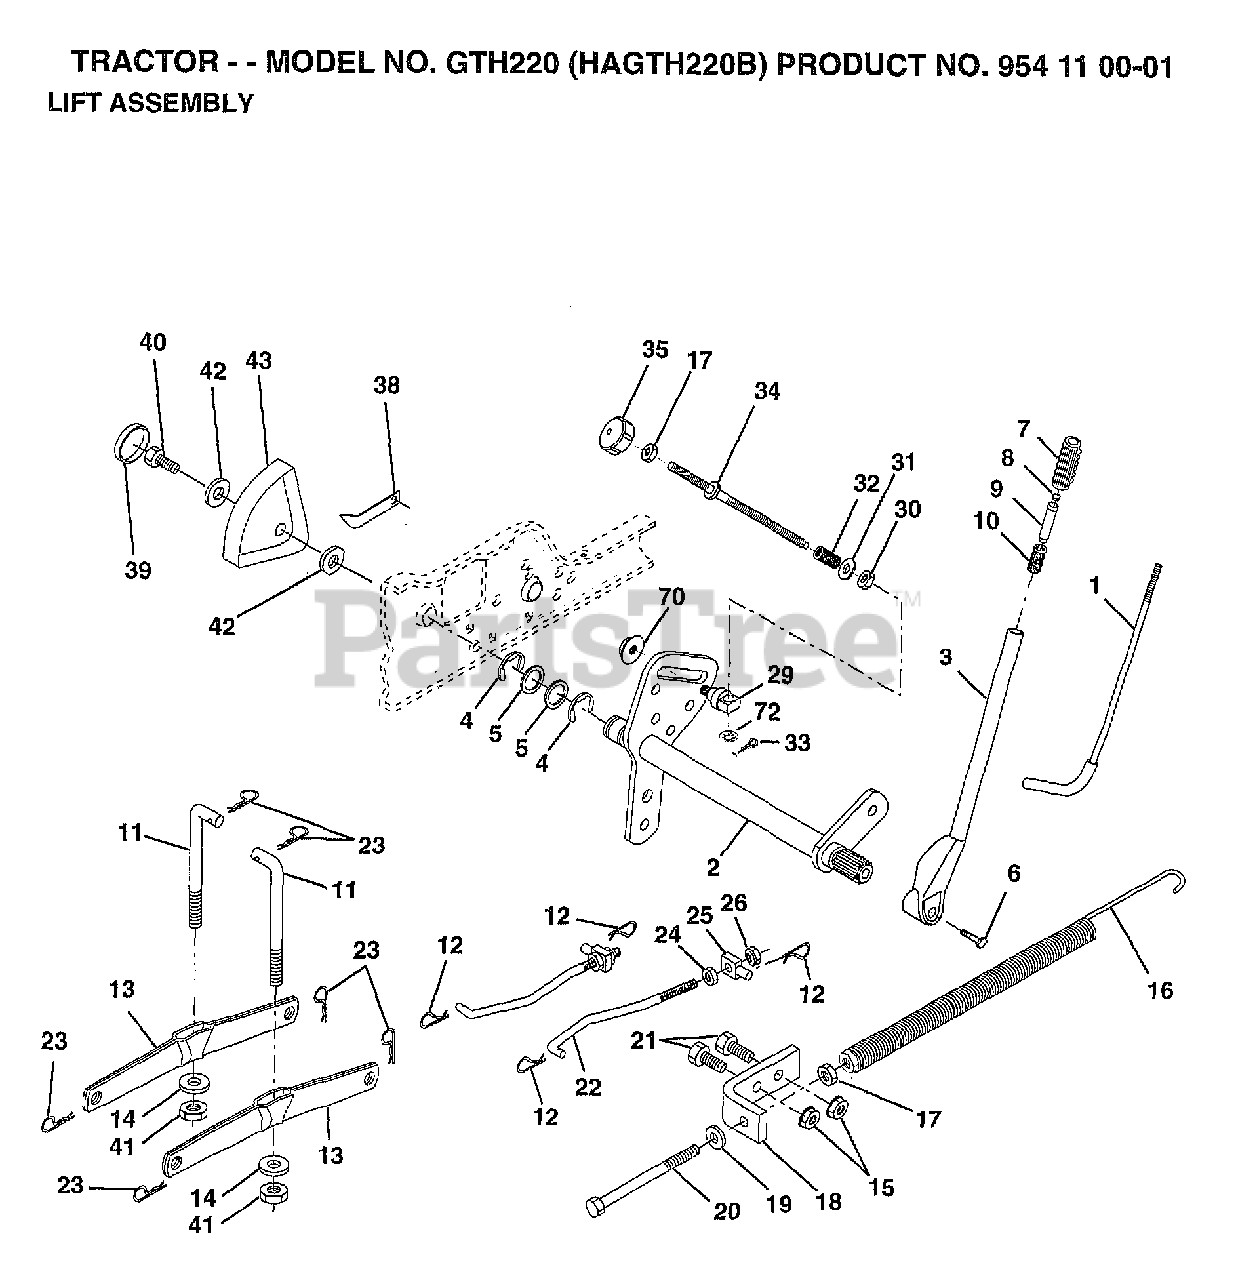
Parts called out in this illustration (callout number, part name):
4	E-RING TRUARC #5133-87
5	WASHER, 29/32 X 1-1/4 X 16 GA.
6	BOLT, FIN HEX 3/8-16 UNC X 1-1/2
15	NUT, CROWNLOCK 3/8-16
17	NUT HEX JAM 3/8-16 UNC
19	WASHER 13/32 X 13/16 X 16 GA
21	BOLT FIN HEX 3/8-16 X 1
24	NUT JAM HEX 1/2-13
26	NUT LOCK W/WSH 1/2-13
31	WASHER, 13/32 X 5/8 X 16 GA.
33	PIN, COTTER 3/32 X 1/2
40	SCREW THDROL 5/16-18 X 3/4 TYT
41	NUT CROWNLOCK 3/8-24
42	WASHER 11/32X1.5X10 GA
